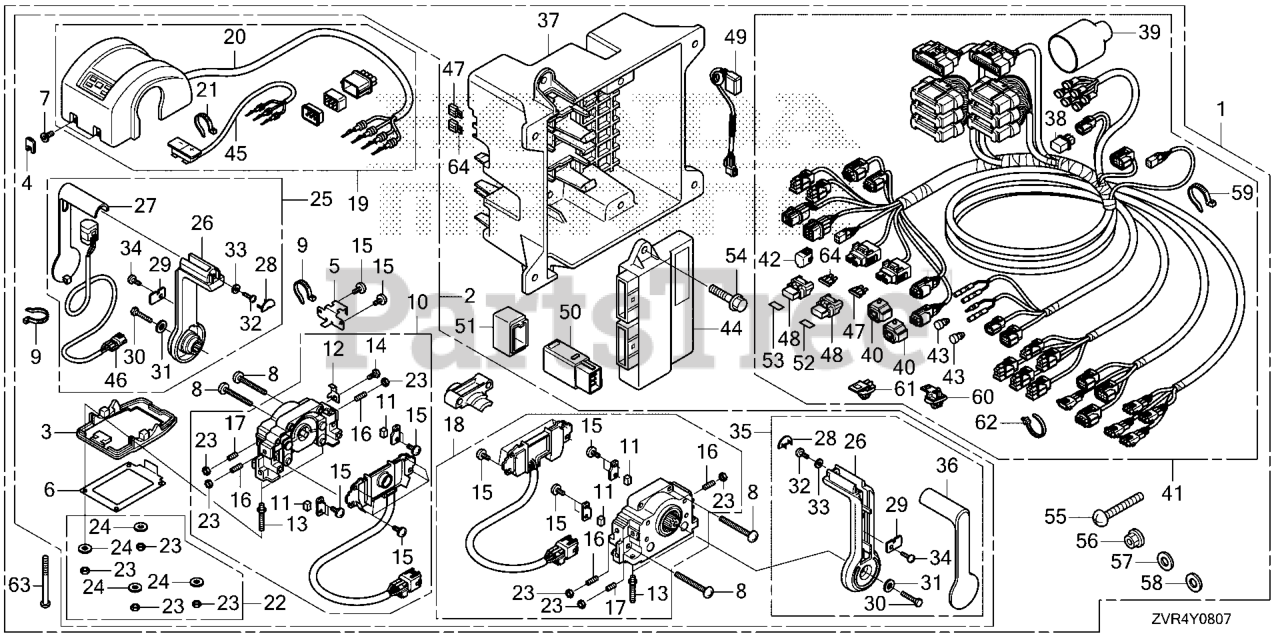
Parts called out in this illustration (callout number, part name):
1	BOX KIT, R/C
2	BOX ASSY., REMOTE CONTROL (TOP MOUNT DUAL)(RH)
3	GASKET (TWIN)
4	COVER, CAP
5	PLATE, COVER FIX (TWIN)
6	SHEET, WATERPROOF (TWIN)
7	BOLT, SOCKET
8	SCREW
9	BAND, NYLON
10	HOUSING ASSY., L.
11	SHOE, BRAKE
12	PLATE, HARNESS
13	BOLT, STUD
14	BOLT
16	SCREW SET
17	SCREW SET
18	HOUSING ASSY., R.
19	COVER ASSY., TWIN
20	LED ASSY., COVER (T)
21	BAND, NYLON
22	NUT SET, MOUNTING
24	WASHER
25	LEVER ASSY., L.
26	LEVER
27	PANEL, LEVER (POWER TRIM-TILT)
28	CAP, LEVER
29	PLATE, LEVER PANEL
30	BOLT
31	WASHER
32	SCREW
33	WASHER
34	SCREW
35	LEVER ASSY., R.
36	PANEL, LEVER
37	CASE, CONTROL UNIT
38	TERMINATOR ASSY.
39	COVER, CONNECTOR (NOT AVAILABLE)
40	SUSPENSION, CONNECTOR
41	CABLE, REMOTE CONTL
42	CAP, DUMMY (WPC 4P 090 M) (RED)
43	PLUG, CONNECTOR (INNER) (TROLLING CONTROL)
44	UNIT ASSY., CONTL
45	SWITCH ASSY., SELECT
46	SWITCH ASSY., POWER TRIM-TILT
47	FUSE, BLADE (3A)
48	COVER ASSY., FUSE
49	RELAY ASSY., CONTROL (NOT AVAILABLE)
50	RELAY ASSY., MAIN
51	SUSPENSION, RELAY
52	LABEL, FUSE (3A)
53	LABEL, FUSE (5A)
54	BOLT, FLANGE (6X20)
55	SCREW, PAN (5X40) DUAL QTY = (8) (SINGLE)
56	NUT, FLANGE (5MM)
57	WASHER, PLAIN (5MM)
58	WASHER, SPG (5MM)
59	HOLDER, CONNECTOR (128.6MM) (NATURAL)
60	CLIP, CONNECTOR (DARK BLUE)
61	CLIP, CONNECTOR (DARK BROWN)
62	CLIP, HARNESS BAND (145MM) (BLACK)
63	SCREW, PAN (5X65)
64	FUSE, MINI (5A)
